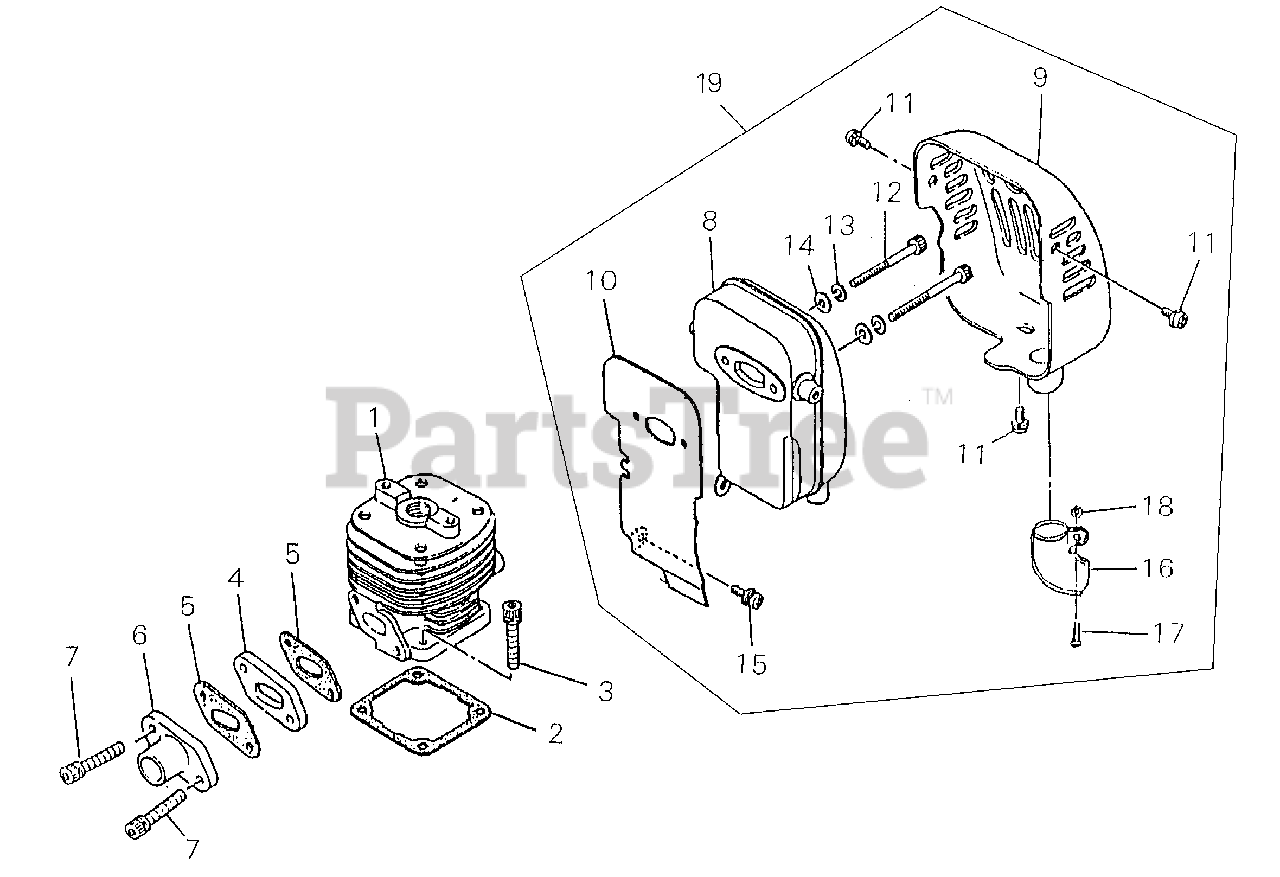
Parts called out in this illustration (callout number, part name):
1	CYLINDER
2	GASKET, CYLINDER
3	SCREW - 5X18
4	INSULATOR
5	GASKET, INTAKE
6	PIPE - INLET
7	SCREW - 5X22
9	COVER, EXHAUST
10	SHIELD, EXHAUST
11	SCREW - 4X8
12	SCREW - 5X50
13	LOCKWASHER - 5
14	WASHER - 5
15	SCREW - 5X12
16	PIPE, EXHAUST
17	SCREW - 4X10
18	NUT - 4
19	MUFFLER ASSY
